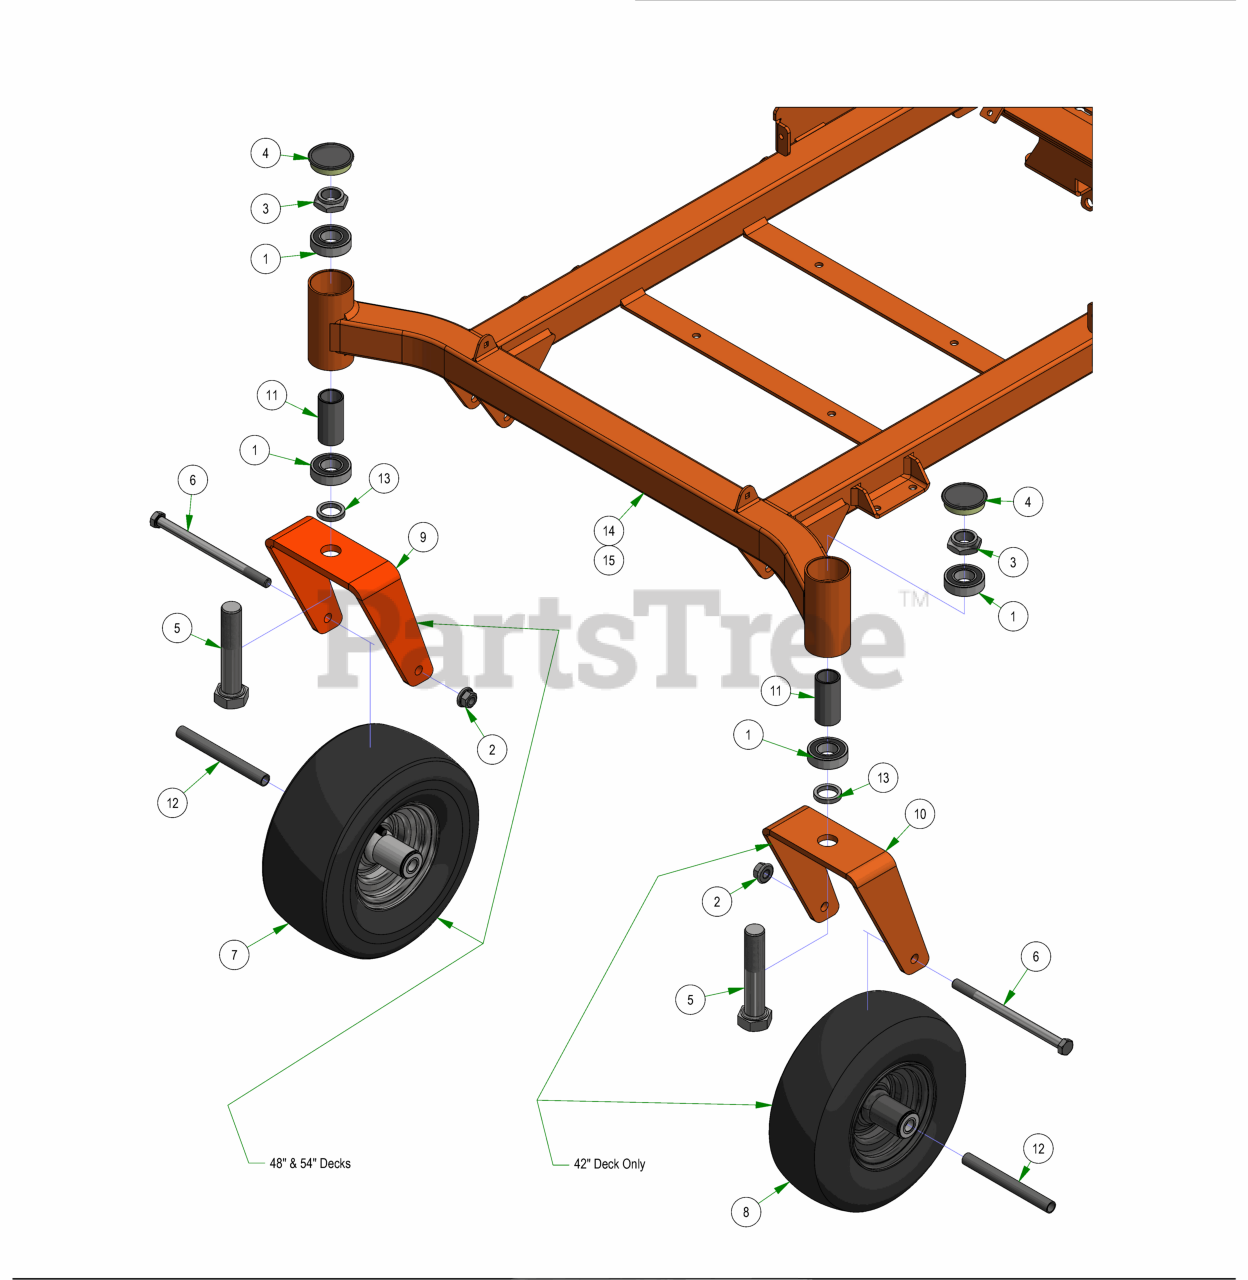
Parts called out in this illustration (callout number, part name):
1	1641 BEARING W/2 CONTACT RUBBER SEALS
2	1/2-13 NYLON INSERT FLANGE LOCKNUT ZINC
3	1"-14 NYLON INSERT JAM LOCKNUT ZINC
4	2017 Bearing Cover
5	1"-14 X 5 HEX CAP SCREW (GR.8) ZINC YELLOW
6	1/2-13 X 7-1/2 HEX CAP SCREW (GR.5) ZINC
7	11x6.00-5 Front Assembly - Black Wheel
8	11 x 4.00 - 5 Front Tire Assembly (Black)
9	2017 MZ Front fork
10	MZ Front Fork (42" ONLY)
11	2016 Front Bearing Spacer
12	Front Wheel Spanner
13	1.02 ID X 1.38 OD X .250 THK SPACER ZINC
14	2025 MZ 42-48 Frame
15	2025 MZ-Avenger 54-60 Frame
